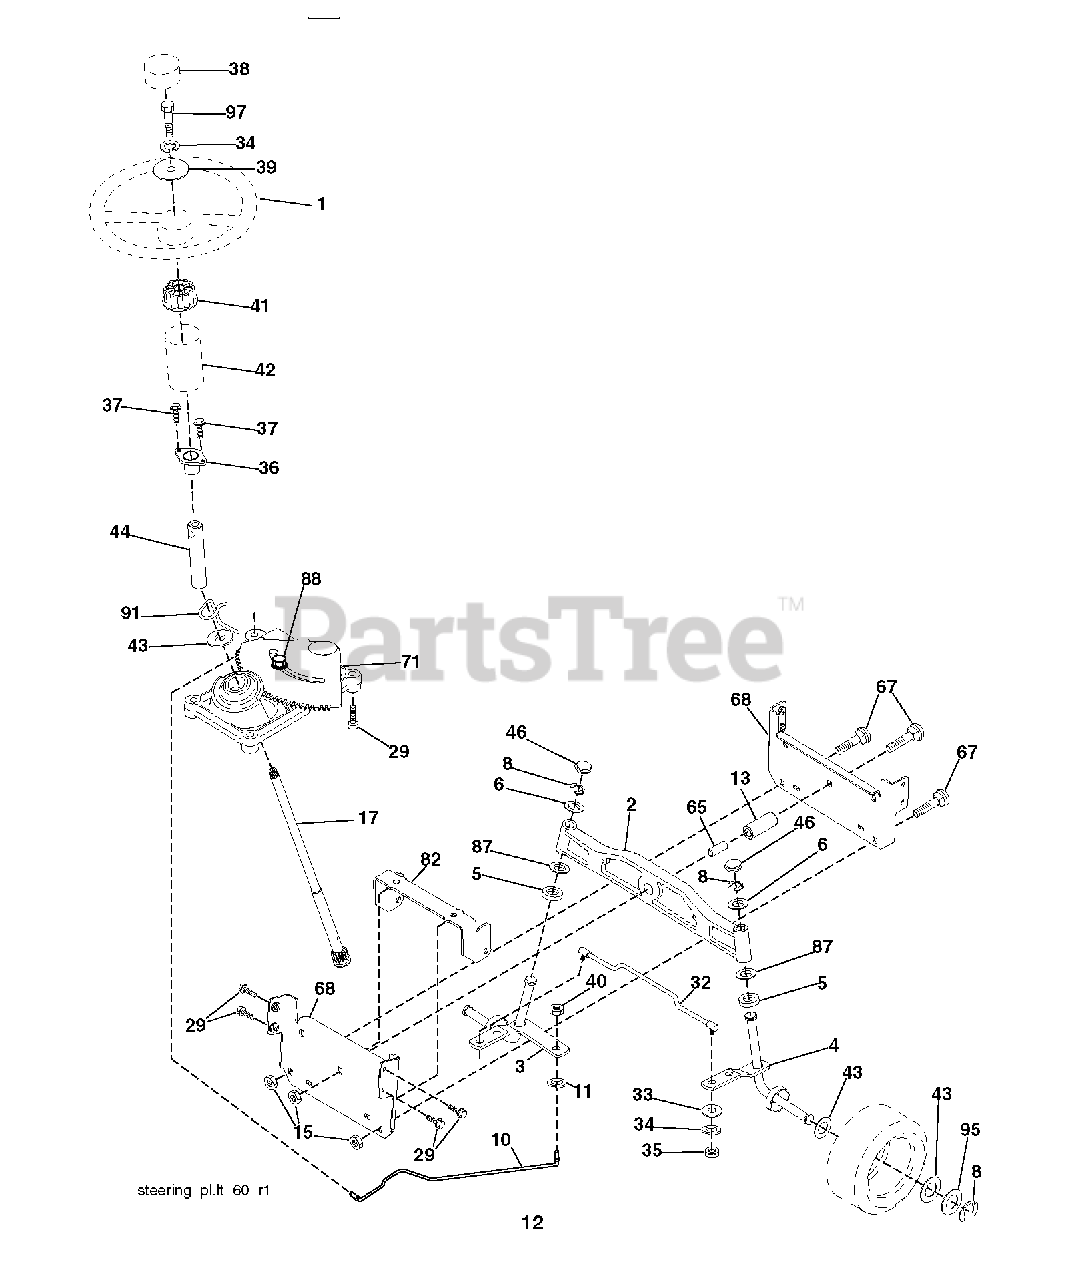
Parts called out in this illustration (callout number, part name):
1	WHEEL.STEERING.OPP.BLACK
2	AXLE ASSY FRONT
3	SPINDLE.ASM.LH.15"TIRES
4	SPINDLE.ASM.RH.15"TIRES
10	DRAGLINK.15".TIRES.2001
11	WASHER, LOCK 3/8
13	TUBE, PIVOT AXLE
15	NUT LOCK FLG 3/8-16 UNC
17	SHAFT STEERING SPLINE
29	SCREW, 3/8-16X3/4
32	ROD.ASM.TIE.BALL.JOINT.NOVAN
33	WASHER M
35	NUT, CROWNLOCK
36	BUSHING, STEERING
38	CAP.WHEEL.STEER.OPP.BLK
40	NUT CROWNLOCK 3/8-24
41	ADAPTER, WHEEL STNG..
42	BOOT.STEERING.SHAFT.BLACK
44	SHAFT.EXTEN.STRG.SPLINE
65	SPACER.BRACE.AXLE
67	BOLT CARRIAGE
68	BRACE.AXLE.15"TIRES
82	BRACKET.SUSP.CHASSIS.FRONT.15
87	WASHER, FLAT .781 X 1 1/2"
88	BOLT, SHOULDER 7/16-20
91	CLIP.STEERING
95	WASHER.HARDENED
97	BOLT 5/16-18 X 4 W/PATCH
